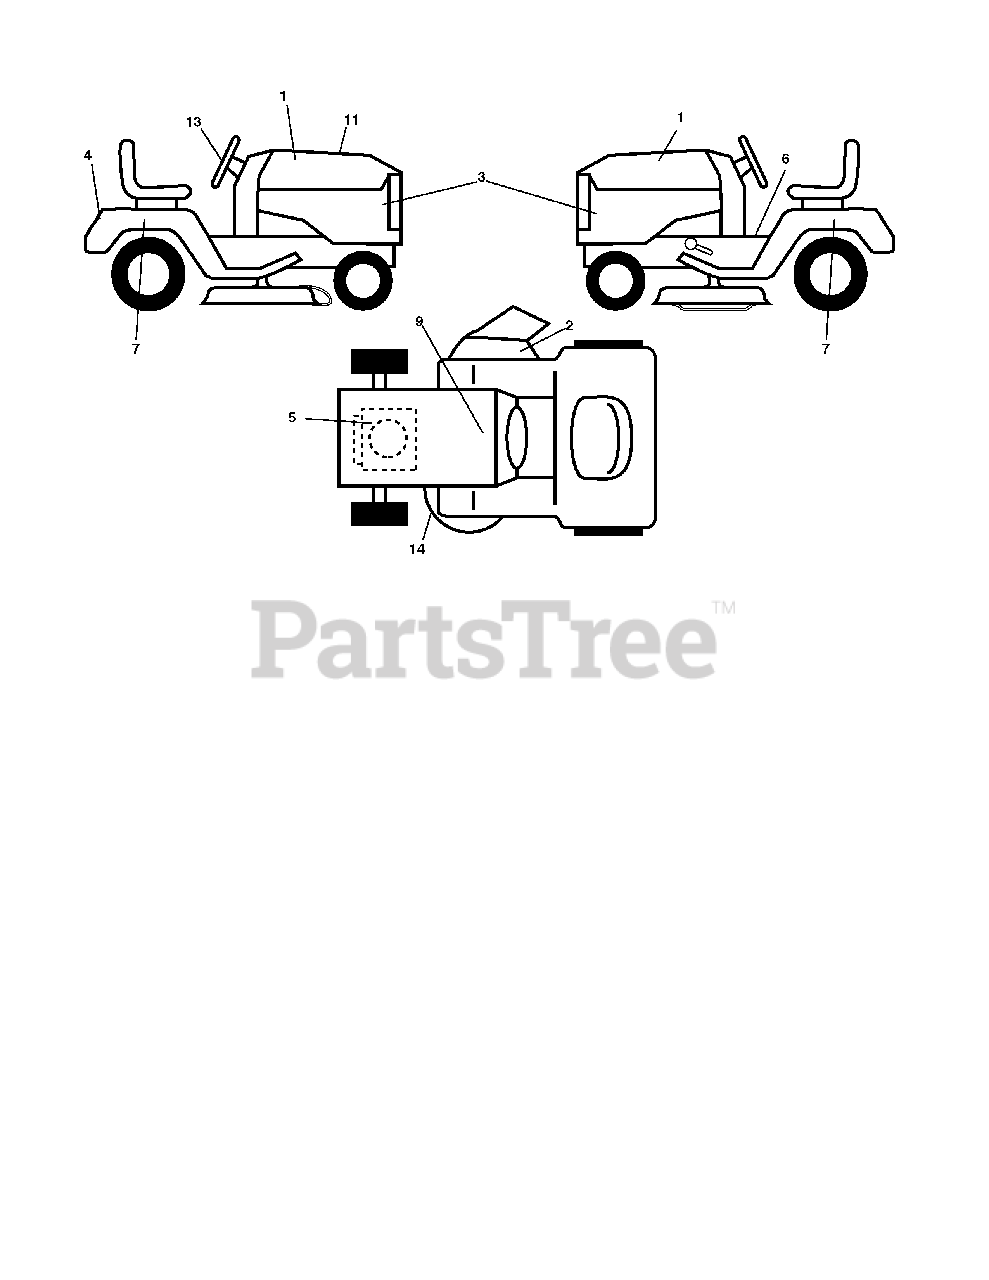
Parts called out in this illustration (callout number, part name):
1	Decal, Hood RH/LH
2	Decal, Keep Hand Away
3	Decal, Side Panel
4	Decal, Fender
5	Decal, Eng H.P.
6	Decal, Fender Operator's
7	Decal, SDFNDR RH/LH
9	Decal, Battery Dnge/Poi
11	Decal, Replacement
13	Decal, Steering Wheel
14	Decal, Mower Schematic
